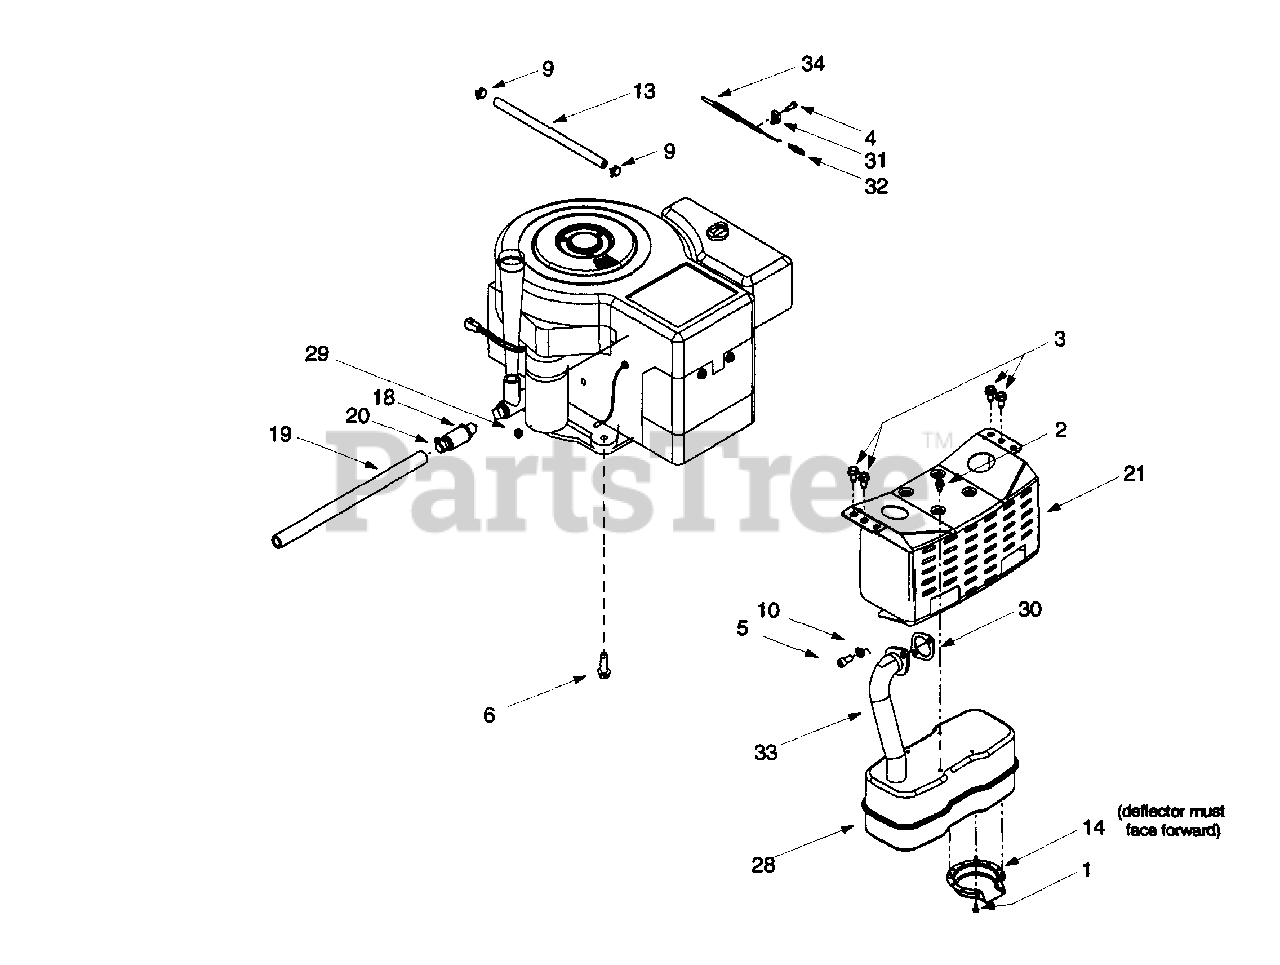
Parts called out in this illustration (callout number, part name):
1	Self Tapping Screw, #8-32 x .375
2	Self Tapping Screw, 1/4-20 x .5
3	Self Tapping Screw, 5/16-18 x .625
4	Screw, #10-32 x .625
5	Socket Cap Screw, 5/16-18 x .625
6	Self Tapping Screw, 3/8-16 x 1.25
9	Hose Clamp
10	Lock Washer, 5/16
13	Fuel Line Hose
14	Muffler Deflector
18	Oil Drain Valve
19	Oil Drain Hose
20	Oil Drain Cap
28	Muffler, Single Inlet
29	Hex Sems Nut, 1/4-20
30	Exhaust Gasket
31	Extension Spring, .275 x 1.25
32	Casing Clamp
33	Exhaust Pipe
34	Throttle/Choke Cable
